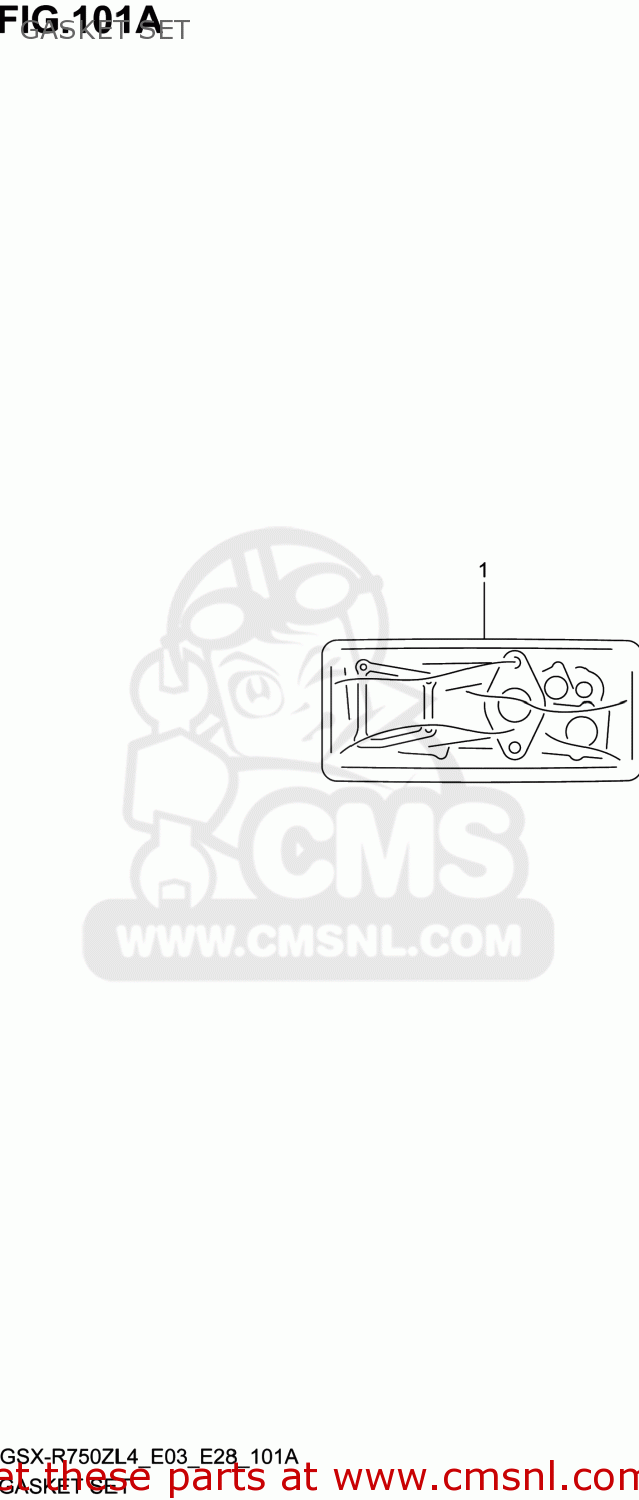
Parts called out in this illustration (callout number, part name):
1	GASKET SET (NAS)
2	GASKET,CYLINDER HEAD (NAS)
3	GASKET,CYL HEAD COVER NO.1 (NAS)
4	GASKET,CYL HEAD COVER NO.2 (NAS)
5	WASHER,CYL HEAD COVER
6	GASKET,CLUTCH COVER (NAS)
7	GASKET,GENERATOR COVER (NAS)
8	GASKET,BREATHER COVER (NAS)
9	GASKET,OIL PAN(ASB) (NAS)
10	GASKET,TENSIONER ADJUSTER (NAS)
11	GASKET,EXHAUST PIPE
12	O RING(D:2.4,ID:15.8)
13	O RING(D:3.1,ID:16.8)
14	O RING(D:2.4,ID:24.7)
15	O RING(D:3.1,ID:32.7)
16	O RING(D:2.6,ID:67.1)
